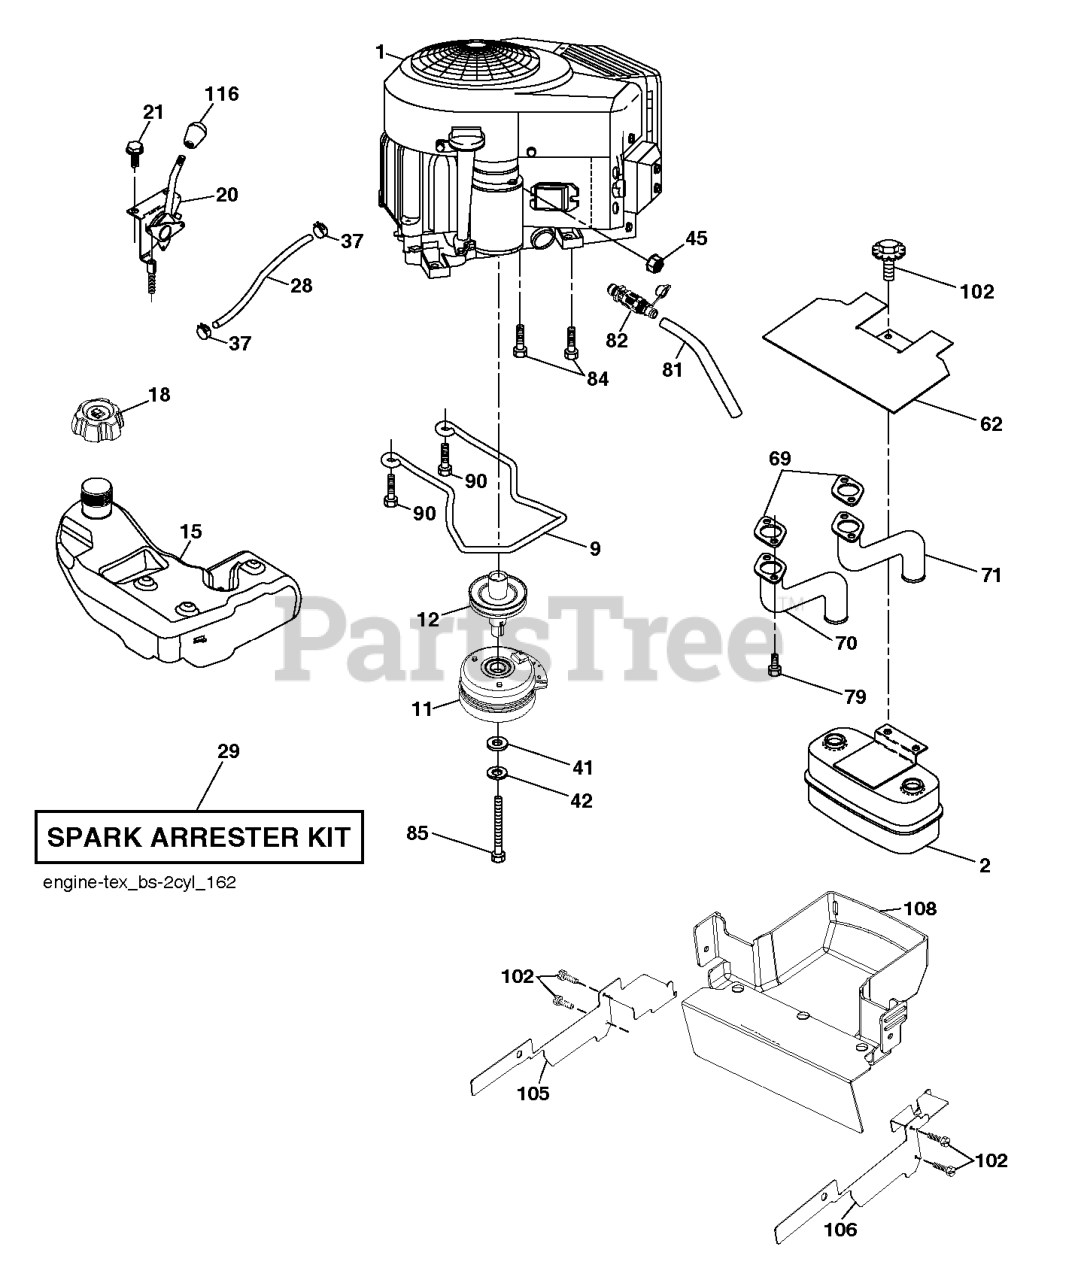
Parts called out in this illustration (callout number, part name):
2	MUFFLER.ASM.TWIN.MNTG.BRACKET
9	KEEPER.BELT.ENG.4.25"2.BLT.431
11	CLUTCH. 5.0 PD. 2.5 OFFSET
12	PULLEY.EXTENDED.SHAFT.GROUND
15	TANK.FUEL.4GAL
18	CAP.ASSY.FUEL.3".N-EPA.GRY.498
20	CONTROL.THROTTLE.PRO.
21	SCREW.#10 X 0.750.BOS
28	REPL BY 532 00 85-43
29	KIT.SPARK ARRESTOR 794945 B&S
37	HOSE CLAMP
42	WASHER 7/16 LOCK
45	NUT
62	SHIELD.HEAT.MUFFLER
69	GASKET.MUFFLER
70	EXHAUST.TUBE.LH.BS/TWIN
71	EXHAUST.TUBE.RH.B&S.TWIN.INTEK
79	SCREW.SOCKET.HEAD.5/16-18
81	TUBE, DRAIN OIL ASM.
82	VALUE.OIL.DRAIN
84	SCREW.3/8-16
85	BOLT.HEX.7/16-20X5.GR5.GREEN
90	SCREW 3/8-16X1
102	SCREW
105	SHIELD 48 CLEARCUT EURO TRACTO
106	SHIELD 48 CLEARCUT EURO TRACTO
108	COVER 48 CLEARCUT EURO TRACTOR
116	KNOB - SHIFT
